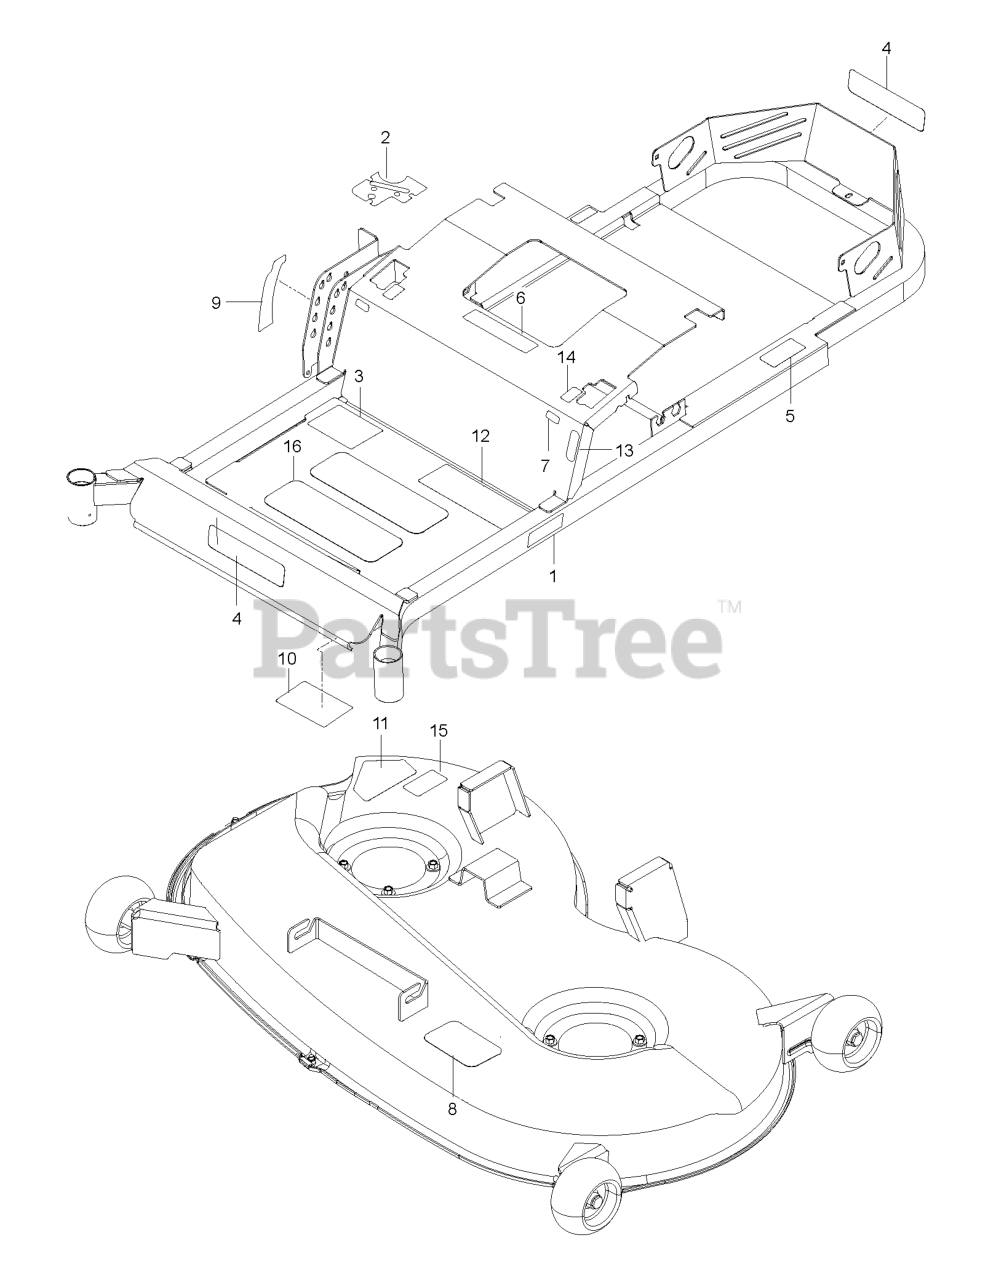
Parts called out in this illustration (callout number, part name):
3	DECAL ZTR STARTING DECAL
4	DECAL.POULAN PRO.YEL/BLK.2017
5	DECAL, DO NOT MOUNT
6	DECAL, BATTERY
7	DECAL.ZTR.TRACKING.GRAPHIC
8	DECAL, BELT ROUTING
9	DECAL.ZTR.HTADJ.LTRD.RZ2015PPR
10	DECAL, SERVICE
11	DECAL, DANGER
12	DECAL ZTR WARNING DECAL DECAL.
13	DECAL.ZTR.TRACKING.GRAPHIC
14	DECAL.ZTR.MTNCONTROL.2015.PPRO
15	DECAL, DECK DEFLECTOR, WARNING
16	ANTI-SKID PAD
